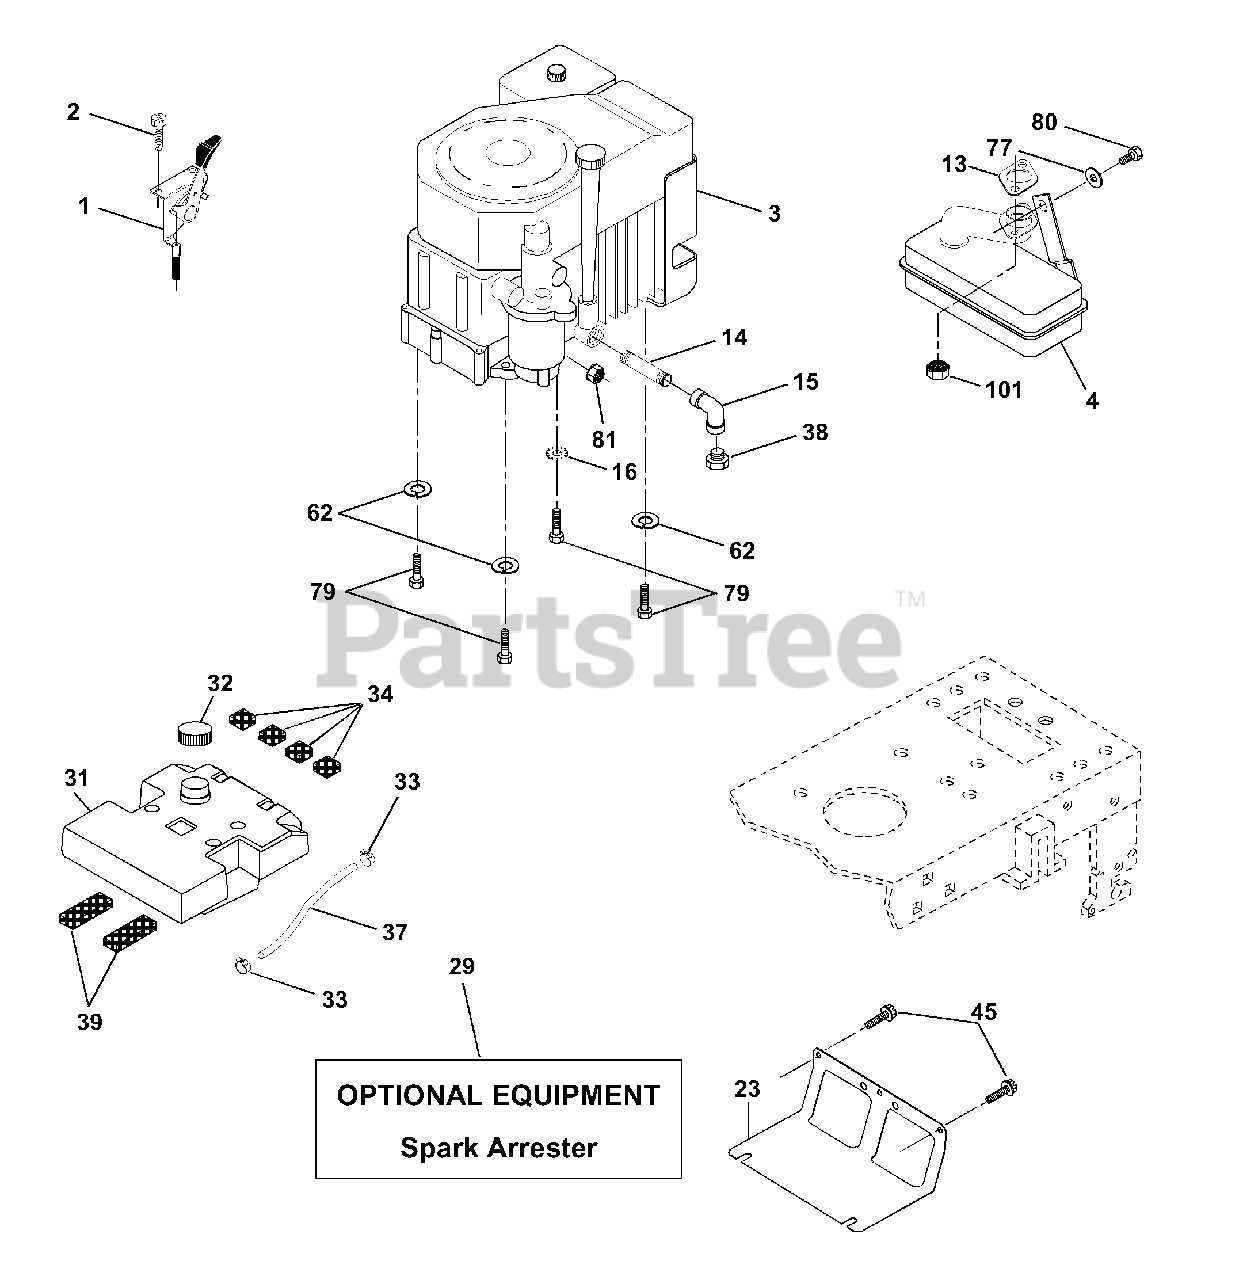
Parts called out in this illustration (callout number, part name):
1	Control Th/ch 27. LH. Flag Dom.
2	Screw Hex Thd Cut 1/4-20x5/8 T
4	Muffler Kohler Single w/Port
13	Gasket Kohler CV13-CV16.5
14	Nipple Pipe 3/8 Npt X 3-1/2
15	Elbow Std 90 Degree 3/8-18 Npt
16	Washer Lock Ext Tooth 5/16
23	Shield BRN/DBR Guard
29	Kit Spark Arrestor (Flat Scrn)
31	Tank Fuel 3.5 STLT W/O Sensor
32	Cap Asm Fuel W/sym Vented
33	Clamp Hose Black
34	Pad Spacer
37	Line Fuel 7.5"
38	Plug Oil Drain
39	Pad Idler 1.75 x .75 x .06
45	Screw 3/8-16 x 3/4
62	Washer Lock Hvy Hlcl Spr 5/16
77	Washer 5/16 x 3/4 x 16 Ga.
79	Bolt Hex
80	Bolt Hex Hd. 5/16-18unc x 1/2
81	Nut Flange 1/4-20 Starter Nut
101	Nut Flange M8-1.25 Non-LK
